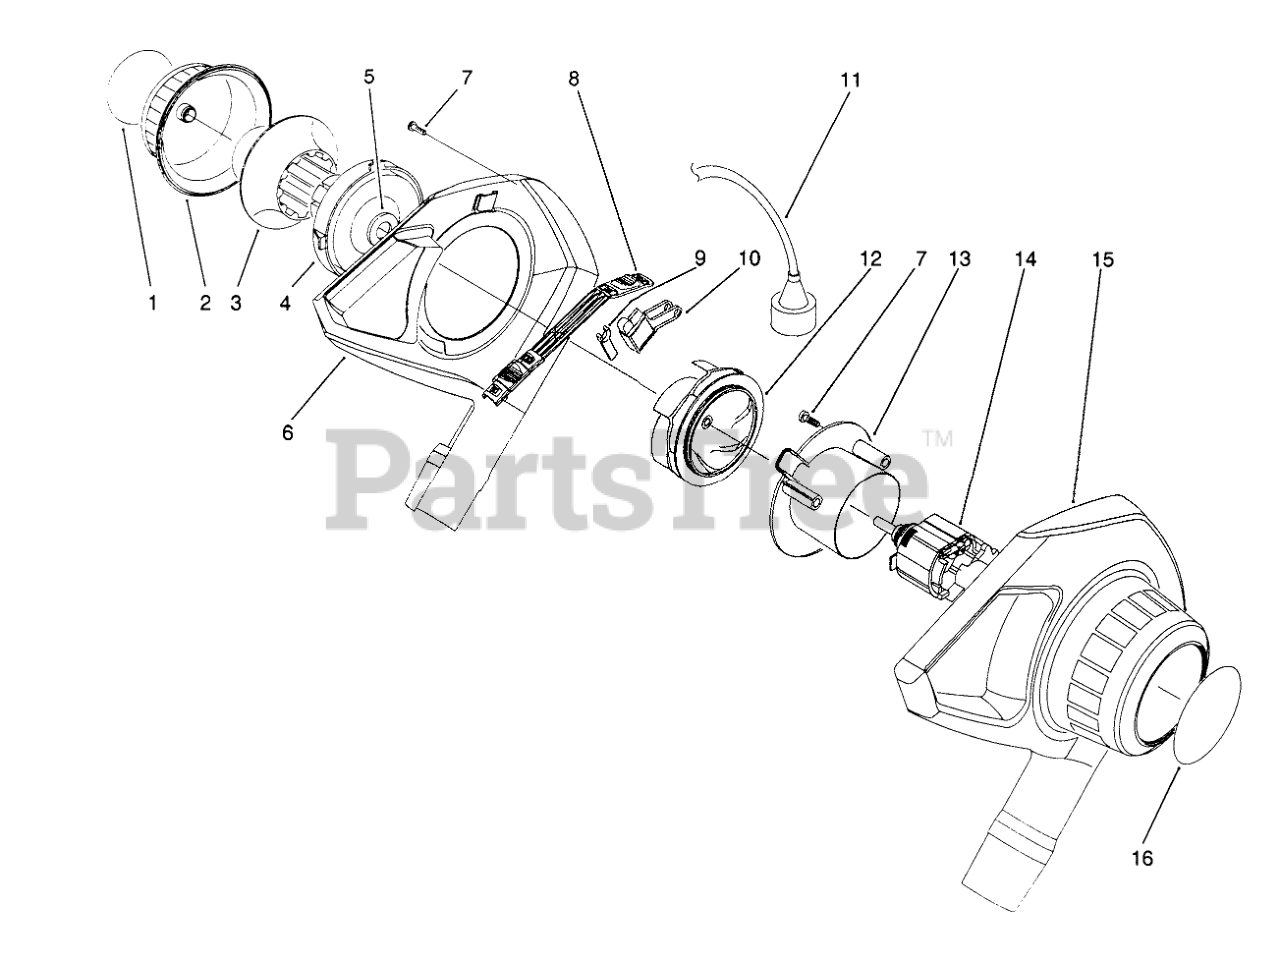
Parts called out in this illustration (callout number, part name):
1	DECAL, 600 CHOKE
2	CHOKE COVER, 600/700
3	MID BL-RING CHOKE
4	MID BL-BASE CHOKE
5	Clip-Retainer
6	HOUSING ASSY, RH
7	Screw
8	SWITCH BAR, 600/700
9	MID BL-ACTUATOR
10	Switch
11	POWER SUPPLY CORD
12	Impeller Assembly
13	Plate-Retaining
14	Motor
15	HOUSING, LH
16	SERIAL DECAL 600
